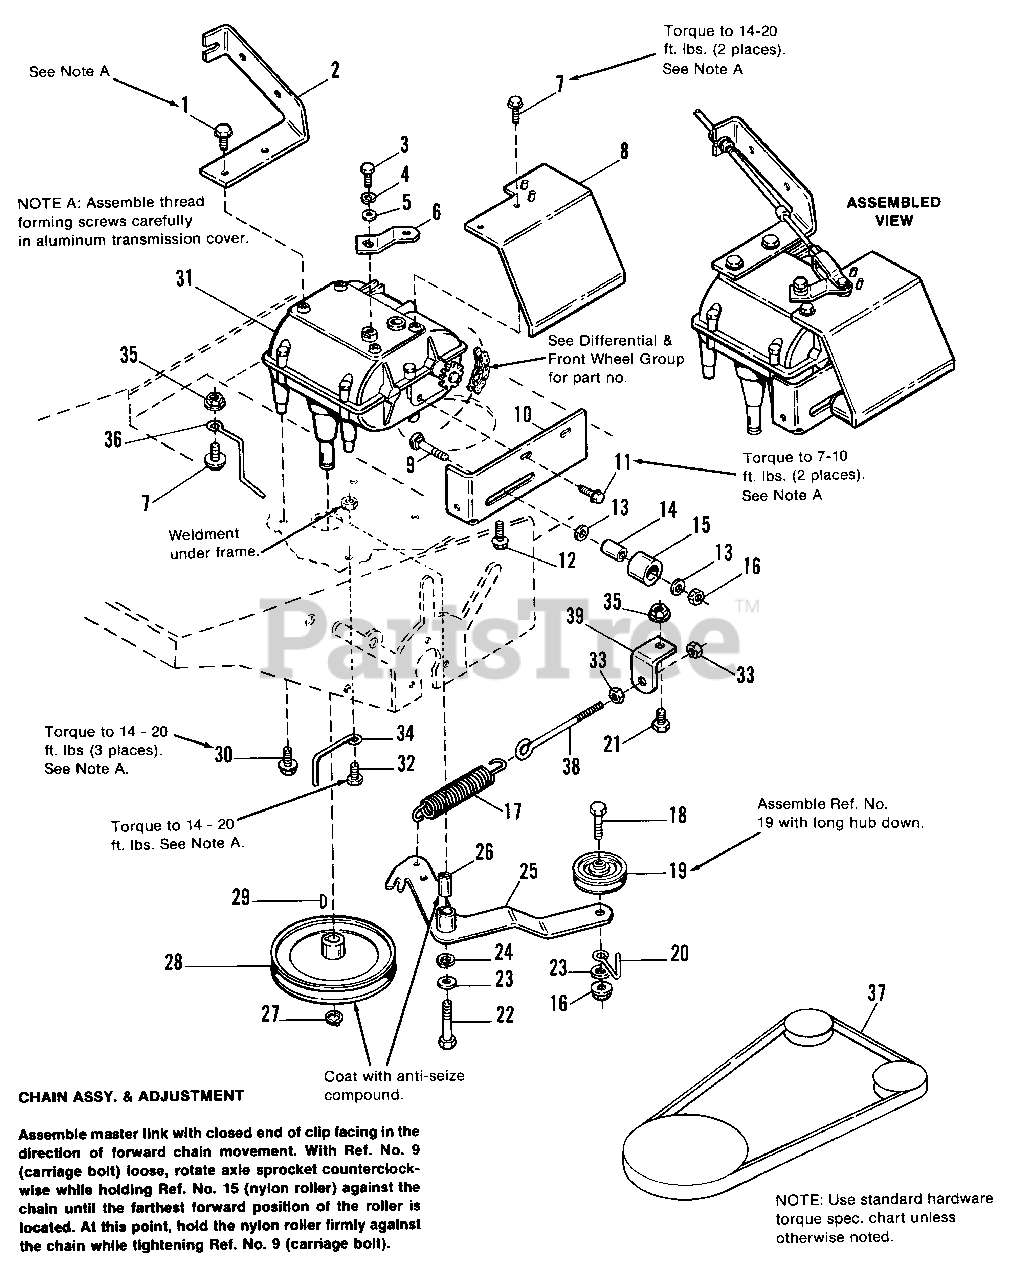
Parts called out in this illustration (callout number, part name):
1	SCREW, Taptite, 5/16-18 x 5/8
2	BRACKET, Cable
3	CAPSCREW, Hex, 1/4-28 x 5/8
4	LOCKWASHER, 1/4
5	WASHER, 5/16
6	LEVER, Shift
7	SCREW, Taptite, 5/16-18 x 1/2
8	GUARD, Chain
9	CARRIAGE BOLT, 3/8-16 x 2.0
10	SUPPORT, Transmission
11	SCREW, Taptite, 1/4-20 x 5/8
12	SCREW, Taptite, 5/16-18 x 3/4
13	WASHER, 3/8
15	ROLLER, Nylon
16	NUT, ESNA Lock, 3/8-16
18	CAPSCREW, 3/8-16 x 1-3/4
19	PULLEY, Idler
21	CAPSCREW, Hex, 5/16-18 x 3/4
22	CAPSCREW, 3/8-16 x 2-1/4
23	WASHER, 3/8
24	LOCKWASHER, 3/8
25	CLUTCH ARM ASSY.
27	RING, Retaining
28	PULLEY ASSY., Transmission
29	KEY, Woodruff No. 9
30	SCREW, Hex Whizlock, 5/16-18 x 3/4
31	TRANSMISSION, 5 Speed
32	SCREW, Taptite, 5/16-18 x 1
33	NUT, Jam, 5/16-18
35	NUT, Hex Whizlock, 5/16-18
36	STOP, Belt
37	BELT, Drive
38	EYEBOLT
